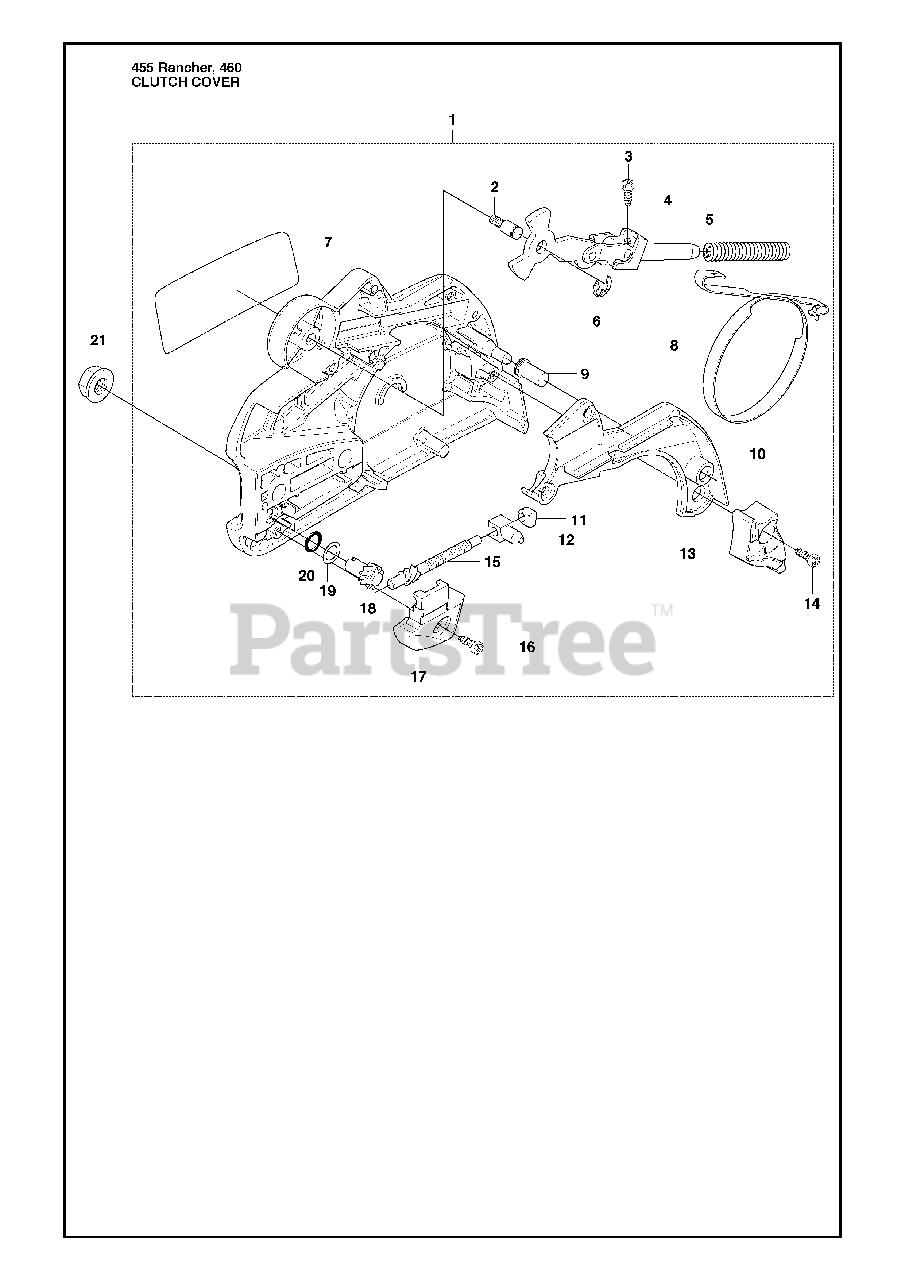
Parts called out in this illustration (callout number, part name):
1	CLUTCH COVER
7	DECAL, CLUTCH COVER
8	BRAKE BAND
15	SCREW
18	WORM WHEEL
21	NUT M8 FLANGE
